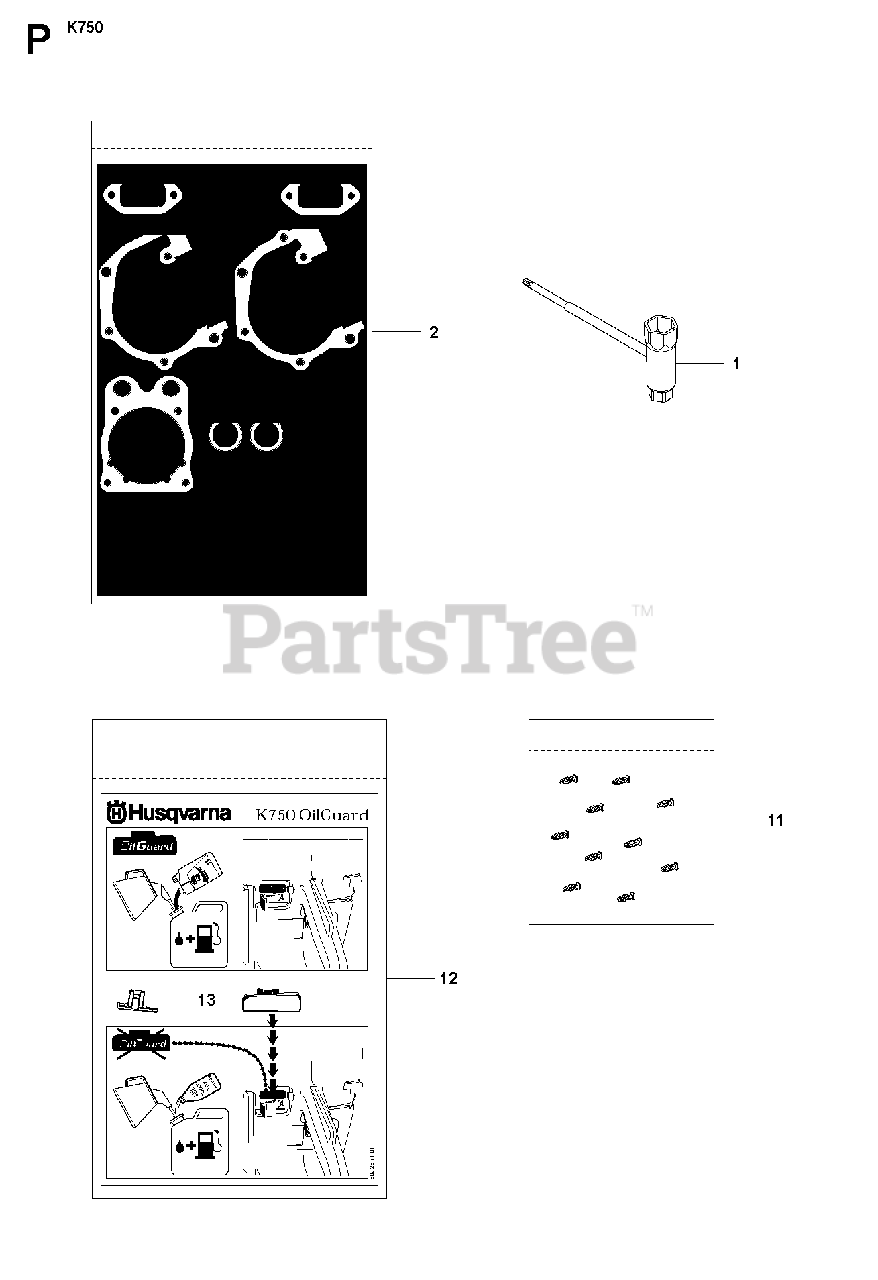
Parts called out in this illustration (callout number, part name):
2	GASKET KITIncl. 3 - 10
4	GASKET
8	SEALING RING
10	GASKET
11	KITIncl. 10 Pins
12	KIT
